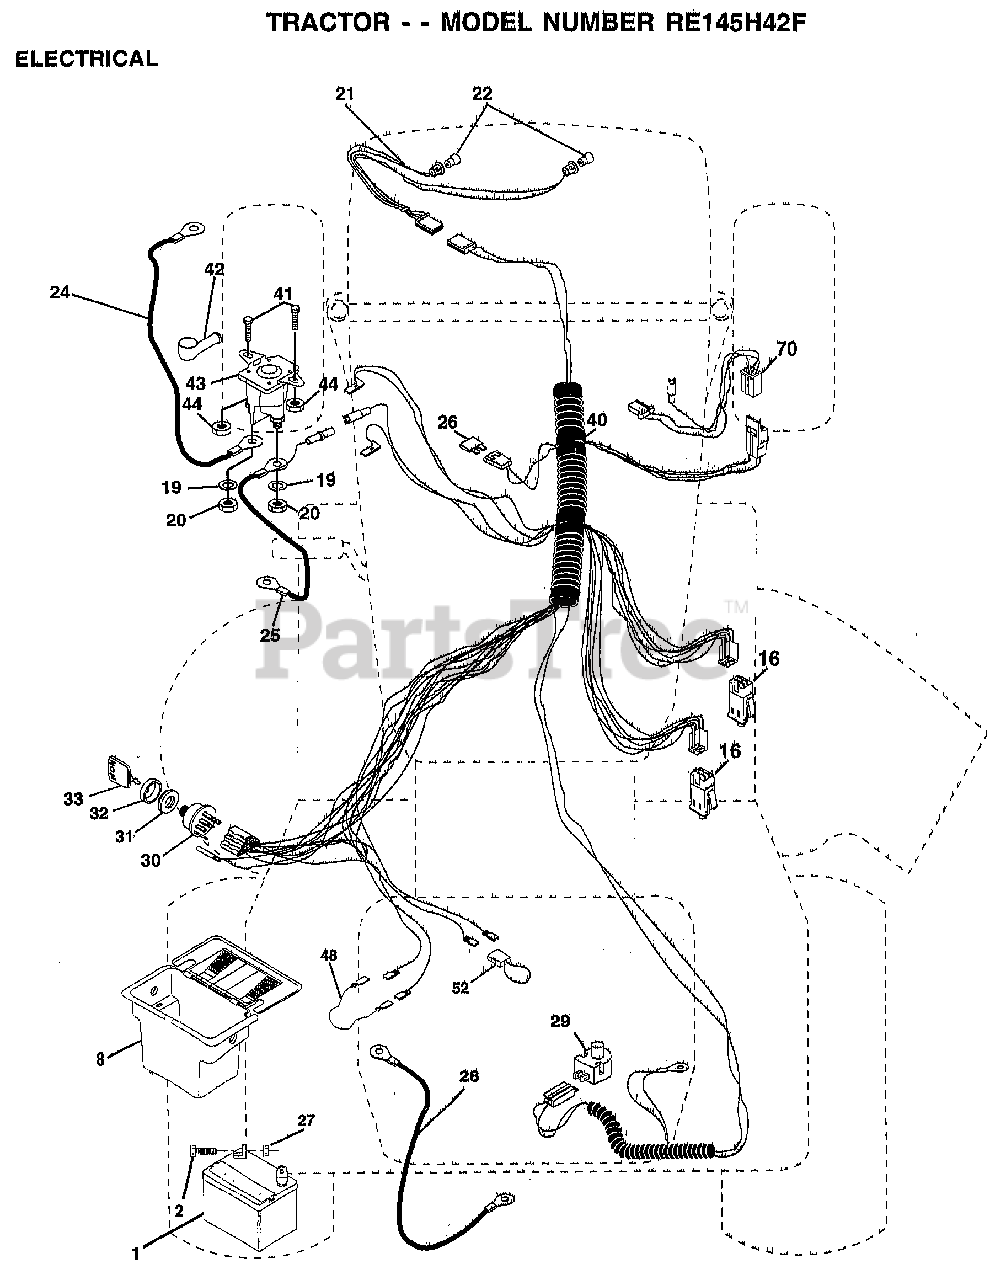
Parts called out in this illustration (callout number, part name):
2	BOLT LT
8	"CASE,BATTERY.MECH"
16	SWITCH INTERLOCK
20	NUT
21	HARNESS.ASM.LIGHT W/4152J
22	HEADLAMP BULB
24	"CABLE T, BATTERY"
25	CABLE.BTRY.6GA.RD
26	FUSE.15 AMP
27	NUT
28	CABLE T
29	SWITCH SEAT
30	SWITCH IGN 4POS
31	NUT IGNITION
32	COVER KEY SWITCH
33	KEY
40	HARNESS.IGNITION
41	BOLT HXHD FIN
44	NUT HXKEP 1/4X20
48	ADAPTER AMMETER
52	PROTECTION LOOP
70	HARNESS.ENGINE
